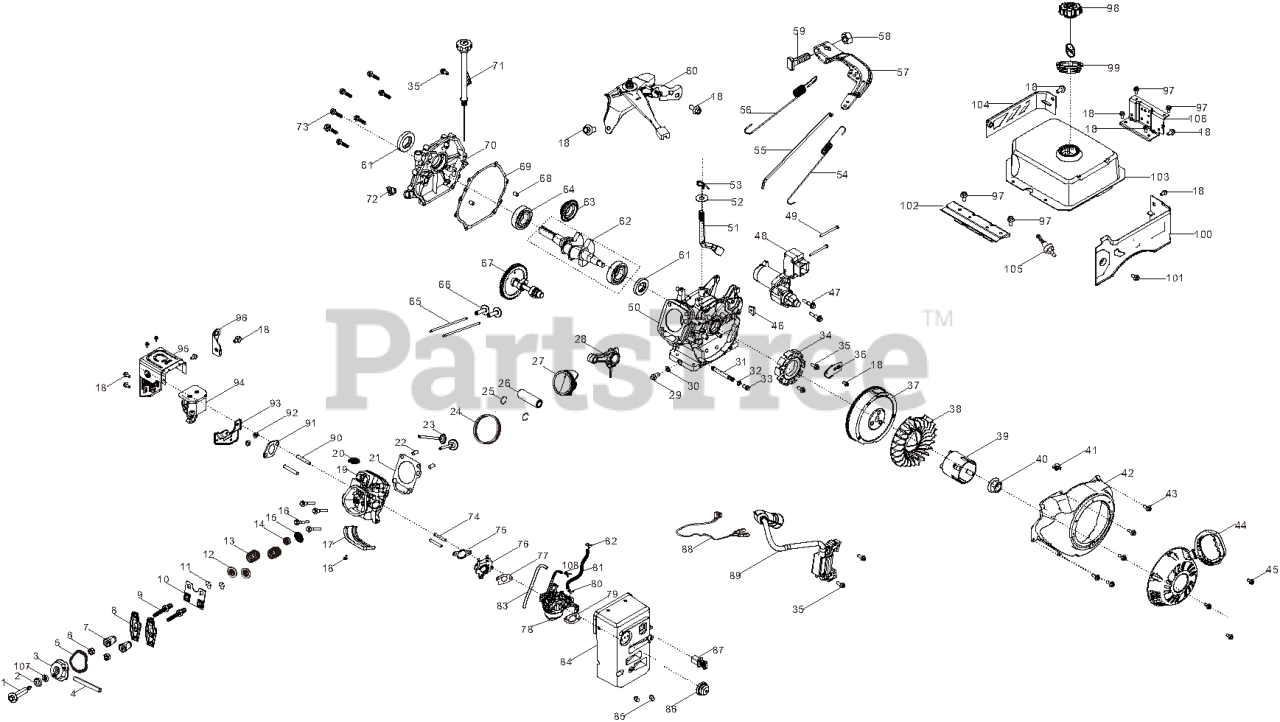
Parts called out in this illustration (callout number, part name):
1	BOLT, VALVE COVER
2	SEAL, VALVE COVER BOLT
3	ASM, CYLINDER HEAD COVER
4	TUBE, BREATHER
5	GASKET, VALVE COVER
6	NUT, VALVE LOCK
7	NUT, VALVE ADJUSTING
8	ROCKER, VALVE
9	ROCKSHAFT BOLT
10	ASM, LIFTER STOPPER PLATE
11	CLAMP, VALVE LOCK
12	SEAT, VALVE SPRING
13	SPRING, VALVE
14	GUIDE, SEAL
15	RETAINER, VALVE SPRING
16	CYLINDER HEAD BOLT
17	SHROUD, CYLINDER BODY
18	BOLT, M6X12 HEX FLANGE
19	ASM, CYLINDER HEAD
20	SPARK PLUG - PLATINUM
21	GASKET, CYLINDER HEAD
22	POSITION PIN
23	VALVES SET
24	RING ASSY, PISTON
25	CLIP, PISTON PIN
26	PIN, PISTON
27	PISTON
28	ROD, CONNECTING
29	BOLT, DRAIN PLUG
30	FLAT WASHER
31	TUBE, OIL DRAIN
32	FLAT WASHER - GRADE A
33	BOLT, DRAIN PLUG
34	COIL SUBASSEMBLY, CHARGE
35	BOLT, M6X28 HEX FLANGE
36	CLAMP, CHARGE COIL
37	FLYWHEEL SUBASSEMBLY
38	IMPELLER
39	CUP, STARTER
40	NUT, FLYWHEEL
41	WIRE CLIP
43	BOLT, M6X12 GRADE B HEX FLANGE
44	STARTER ASSY, RECOIL
45	BOLT, M6X8 HEX FLANGE
46	PLUG, RUBBER
47	BOLT, M8X40 HEX FLANGE
48	STARTING MOTOR ASSEMBLY
49	SCREW, PAN HEAD M4X55X0.7
51	ARM, GOVERNOR
52	FLAT WASHER
53	COTTER PIN
54	SPRING, THROTTLE VLV RETURNING
55	ROD, GOVERNEOR
56	SPRING, GOVERNOR
57	ASM, GOVERNOR BRACKET
58	HEXAGON NUT WITH FLANGE
59	BOLT, GOVERNOR SUPPORT
60	CONTROL ASSY, THROTTLE
61	SEAL, OIL
62	CRANKSHAFT ASSY
63	GEAR ASSY, GOVERNOR
64	BRG, DEEP GROOVE BALL
65	ROD, PUSH
66	TAPPET, VALVE
67	CAMSHAFT ASSY
68	POSITION PIN
69	GASKET, CRANKCASE
70	COVER, CRANKCASE
71	DIPSTICK SUBASSEMBLY, OIL
72	ASM, ENGINE OIL PLUG
73	BOLT, M8X35 HEX FLANGE
74	STUD BOLT (BM=2D)
75	GASKET, INLET
76	PLATE, CARBURETOR INSULATOR
77	CARBURETOR SEAL GASKET
78	CARBURETOR ASSY
79	AIR CLEANER SEAL GASKET
80	PIPE CLAMP
81	TUBE, FUEL
82	PIPE CLAMP
83	LINE, PRIMER
84	ASM, CONTROL PANEL
85	ACORN HEXAGON NUTS
86	BULB, PRIMER
87	ASM, STOP ENGINE SWITCH
88	WIRE, IGNITION COIL STOP ENG
89	COIL, IGNITION
90	STUD BOLT (BM=2D)
91	GASKET, EXHAUST OUTLET
92	LOCK NUT
93	MOUNTING BRACKET
94	MUFFLER ASSY
95	SHIELD, HEAT
96	TRANSPORT HANGER
97	BOLT, M8X20 HEX FLANGE
98	CAP, FUEL
99	FUEL GAUGE
100	SHIELD,FUEL TANK
101	BOLT, M6X16 HEX FLANGE
102	FUEL TANK INSTALL REAR BRKT
103	FUEL TANK
104	FUEL TANK SHIELD 2
105	OUTLET WITH FILTER
106	FRAME, FUEL TANK INSTALLATION
NS	KIT,301CC 3000-6000FT CARB JET
NS	KIT,301CC 6000-8000FT CARB JET
